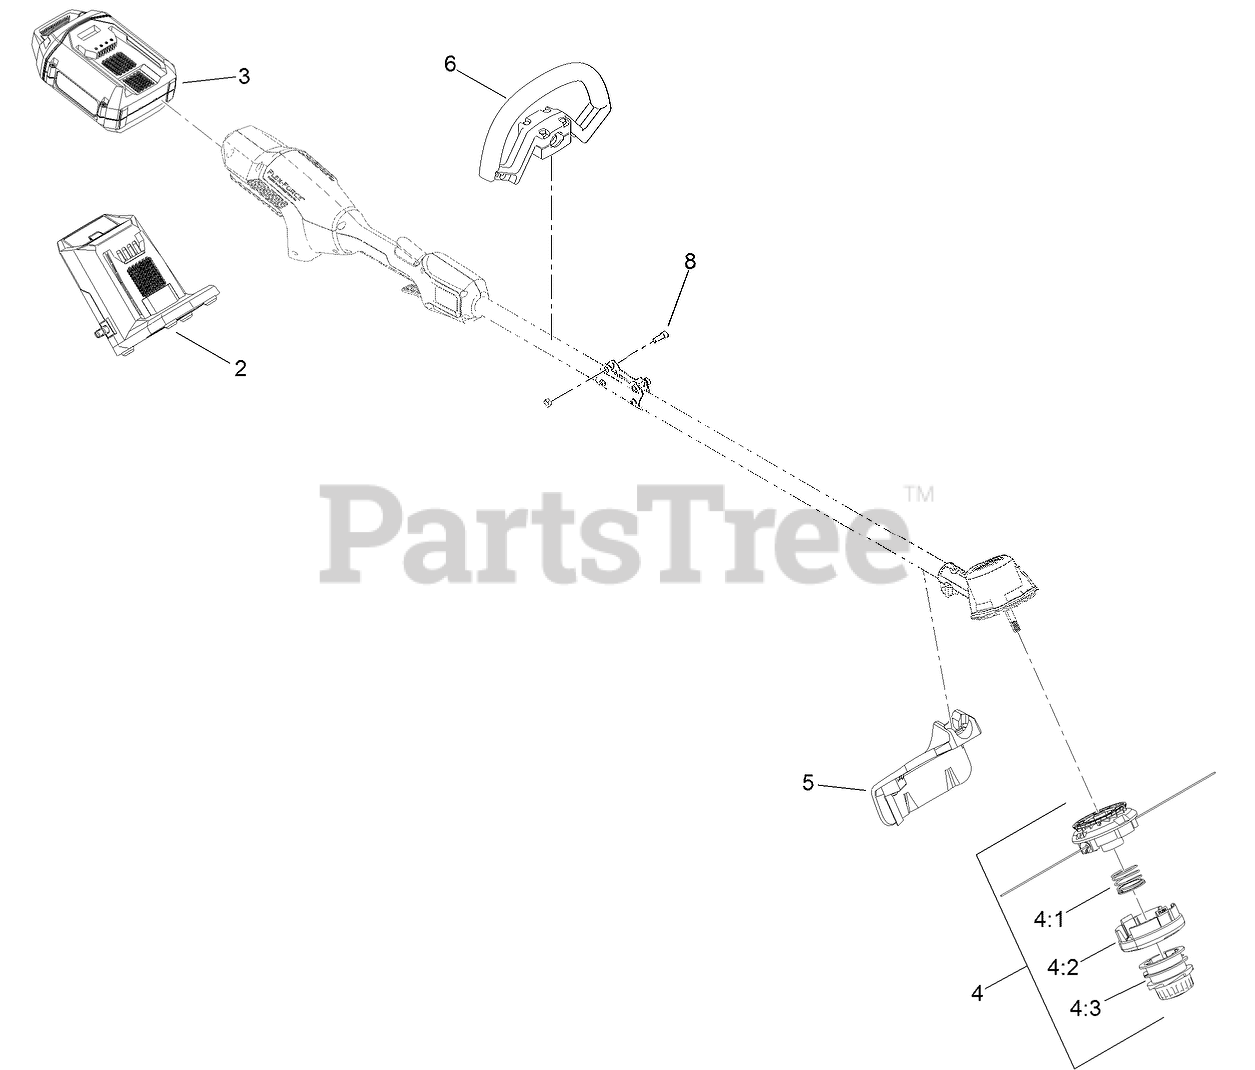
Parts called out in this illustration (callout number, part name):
2	CHARGER-BATTERY, 60V 2 AMP
3	BATTERY-LI ION, 60V 2.5 AH
4	BUMP FEED HEAD ASM
4:1	SPRING-SPOOL
4:2	CAP-FEED, BUMP
5	SHIELD-GRASS
6	HANDLE-TRIMMER
8	SCREW-HSH
